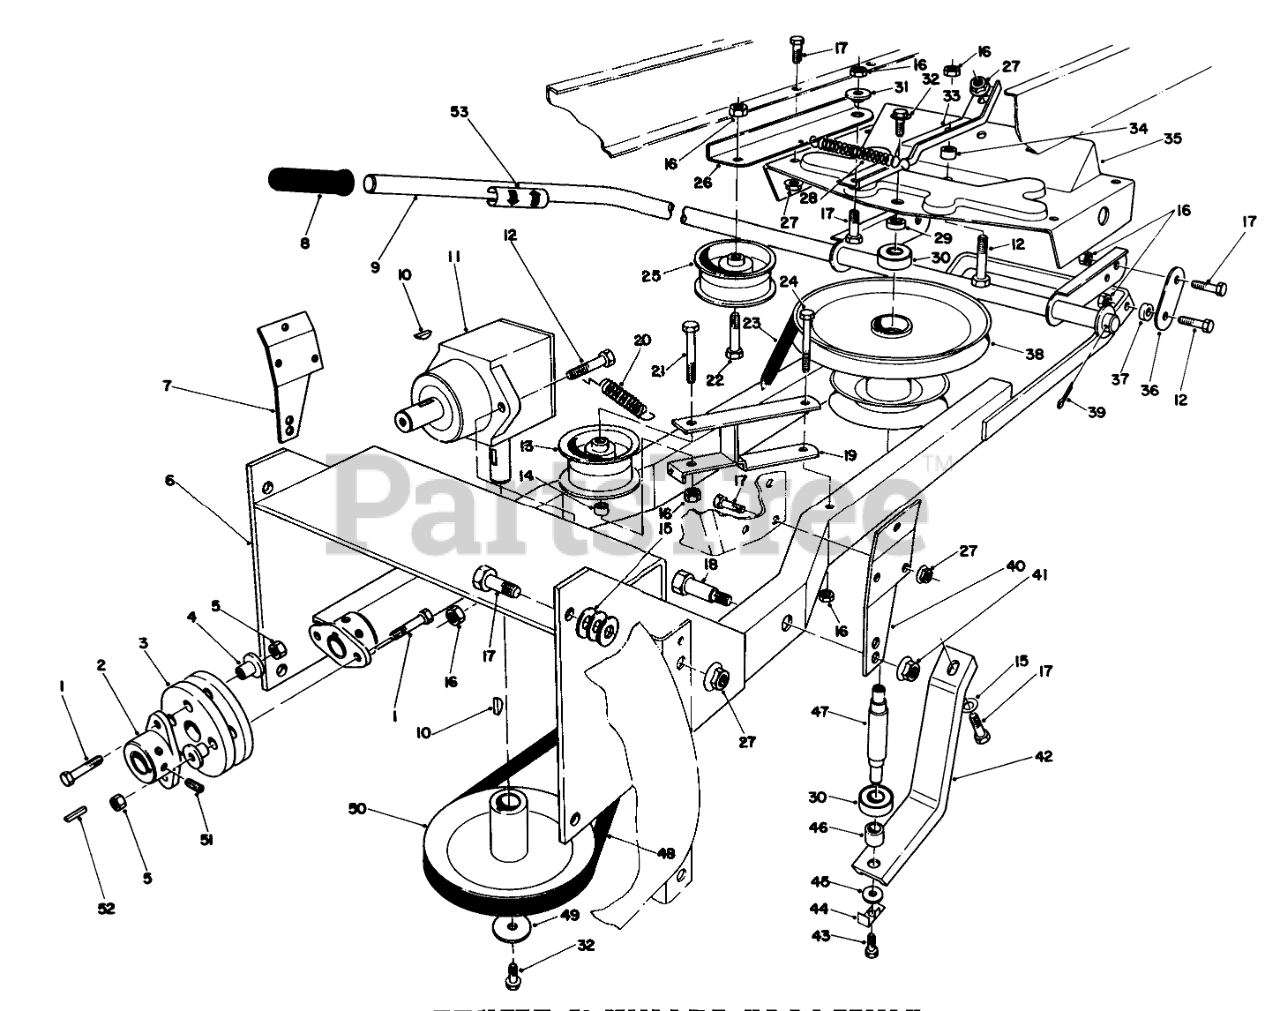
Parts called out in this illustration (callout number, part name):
1	SCREW-HH
2	HUB-COUPLER
3	RUBBER COUPLING
4	Spacer-Rubber Coupling
5	NUT-LOCK, NI
6	Carrier Frame
7	RH FRONT BRKT R
8	Handle Grip
9	Handle-Lift
10	KEY-WOODRUFF
11	Gear Case Assembly
12	SCREW-HH
13	IDLER
14	SPACER
15	WASHER-FLAT
16	NUT-LOCK, NI
17	SCREW-HH
18	SHOULDER BOLT
19	FRT IDLER ARM WA B
20	EXTENSION SPRING
21	SCREW-HH
22	SCREW-HH
23	V-BELT
24	SCREW-HH
25	IDLER BO
26	REAR IDLER ARM B
27	NUT-HHF, WHIZ
28	EXTENSION SPRING
29	UPPER SPACER
30	BEARING-BALL
31	Spacer-Idler Arm
32	SCREW-HHF
33	Support-Frame
34	SPACER
35	REAR FRAME
36	Lift Linkage-Lower
37	SPACER
38	Spindle Housing Assembly
39	PIN-COTTER
40	LH FRONT BRKT R
41	FLANGE NUT 1/2 - 13
42	SHAFT SUPPORT B
43	SCREW-HH
44	Locking Tab
45	WASHER-FLAT
46	Spacer-Lower
47	Shaft-Spindle
48	V-BELT
49	HUB WASHER
50	Pulley
51	SCREW-HSH
52	SQUARE KEY
53	Decal-Lift Control
